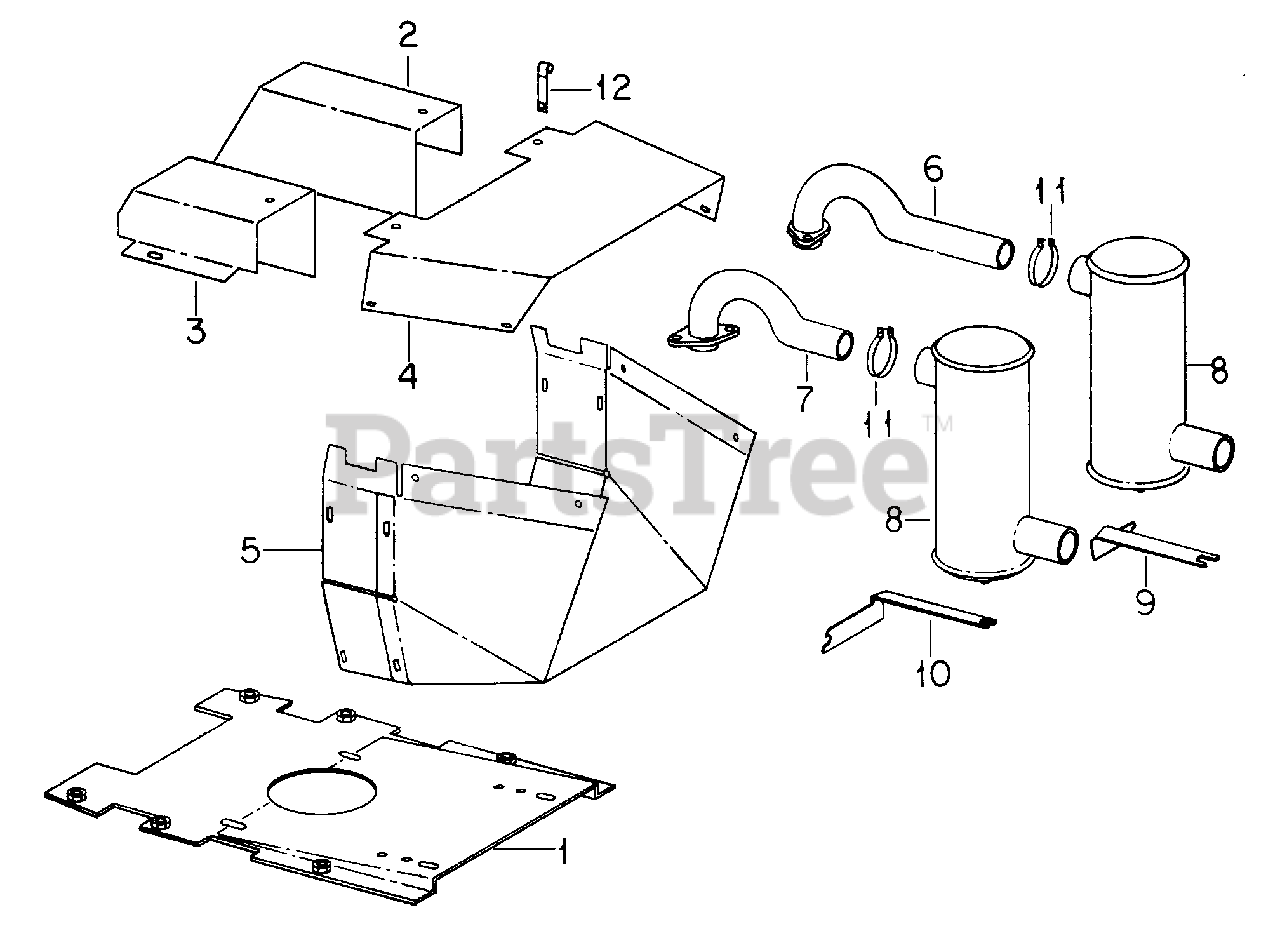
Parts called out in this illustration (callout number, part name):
1	Plate Assy, Eng Mtg
2	Cover Assy, Exhaust Tube, LH
3	Cover Assy, Exhaust Tube, RH
4	Duct, Top Cooling
5	Duct Assy, Bottom Cooling
6	Tube Assy, Exhaust, LH
7	Tube Assy, Exhaust, RH
9	Support, Muffler, RH
10	Support, Muffler, LH
11	Clamp, Muffler
